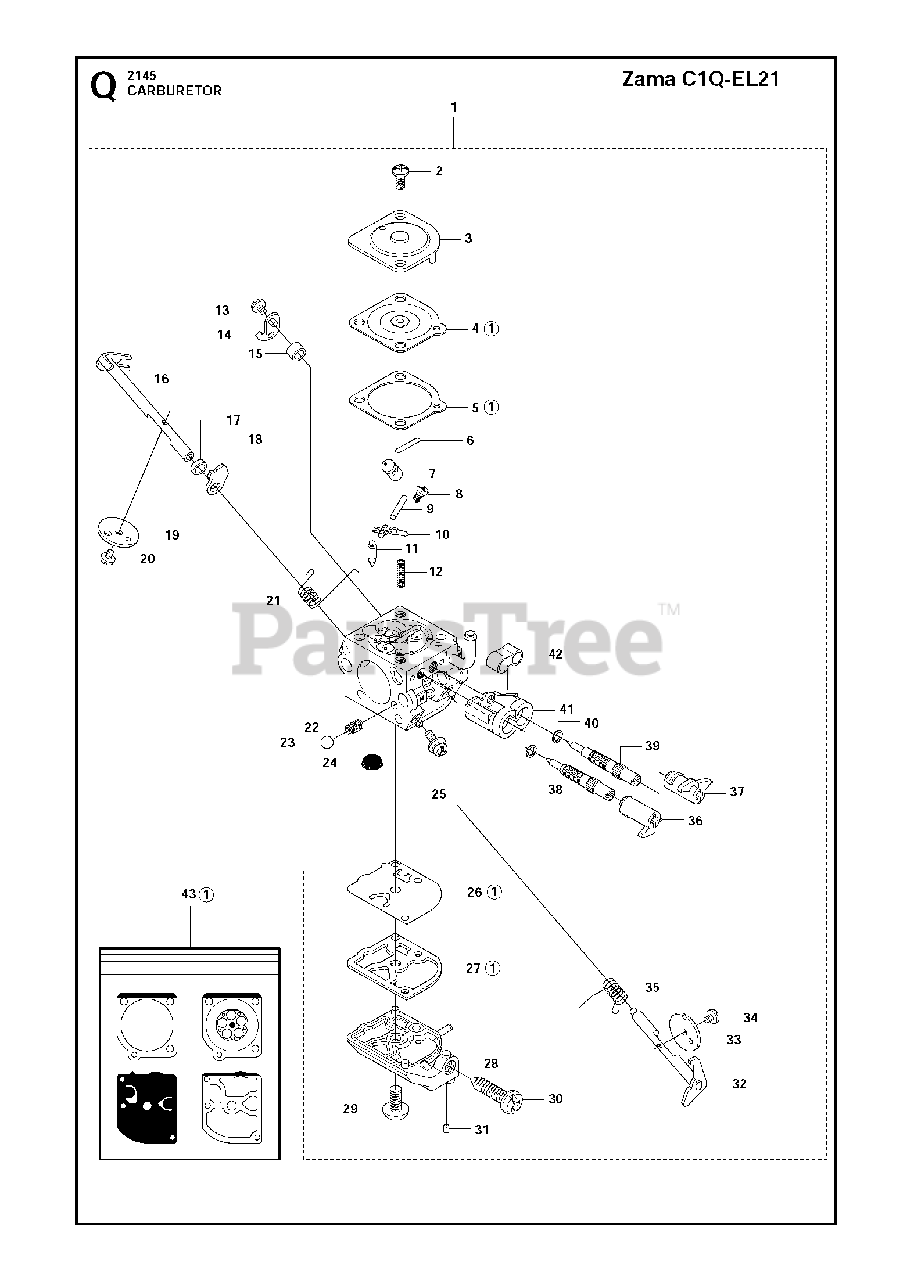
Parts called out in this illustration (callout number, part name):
1	CARBURETOR
2	SCREW
3	COVER
4	METERING DIAPHRAGM
5	GASKET METERING SIDE
6	PLUG
7	SPREADER
8	SCREW
9	PIN FULCRUM
10	LEVER
11	INLET NEEDLE
12	SPRING
13	SCREW
14	LEVER
15	SPACER
16	CHOKE SHAFT
17	BUSHING *
18	LEVER
19	DISC
20	SCREW
21	SPRING
22	SPRING
23	BALL
24	STRAINER
25	SCREW *
26	PUMP DIAPHRAGM
27	GASKET
28	COVER
29	SCREW
30	SCREW
31	PLUG
32	THROTTLE SHAFT
33	THROTTLE FLAP
34	SCREW
35	SPRING
36	LIMITER CAP
37	LIMITER CAP
38	NEEDLE HIGH SPEED
39	NEEDLE LOW SPEED
40	WASHER
41	SLEEVE
42	SLEEVE
43	GASKET SET
